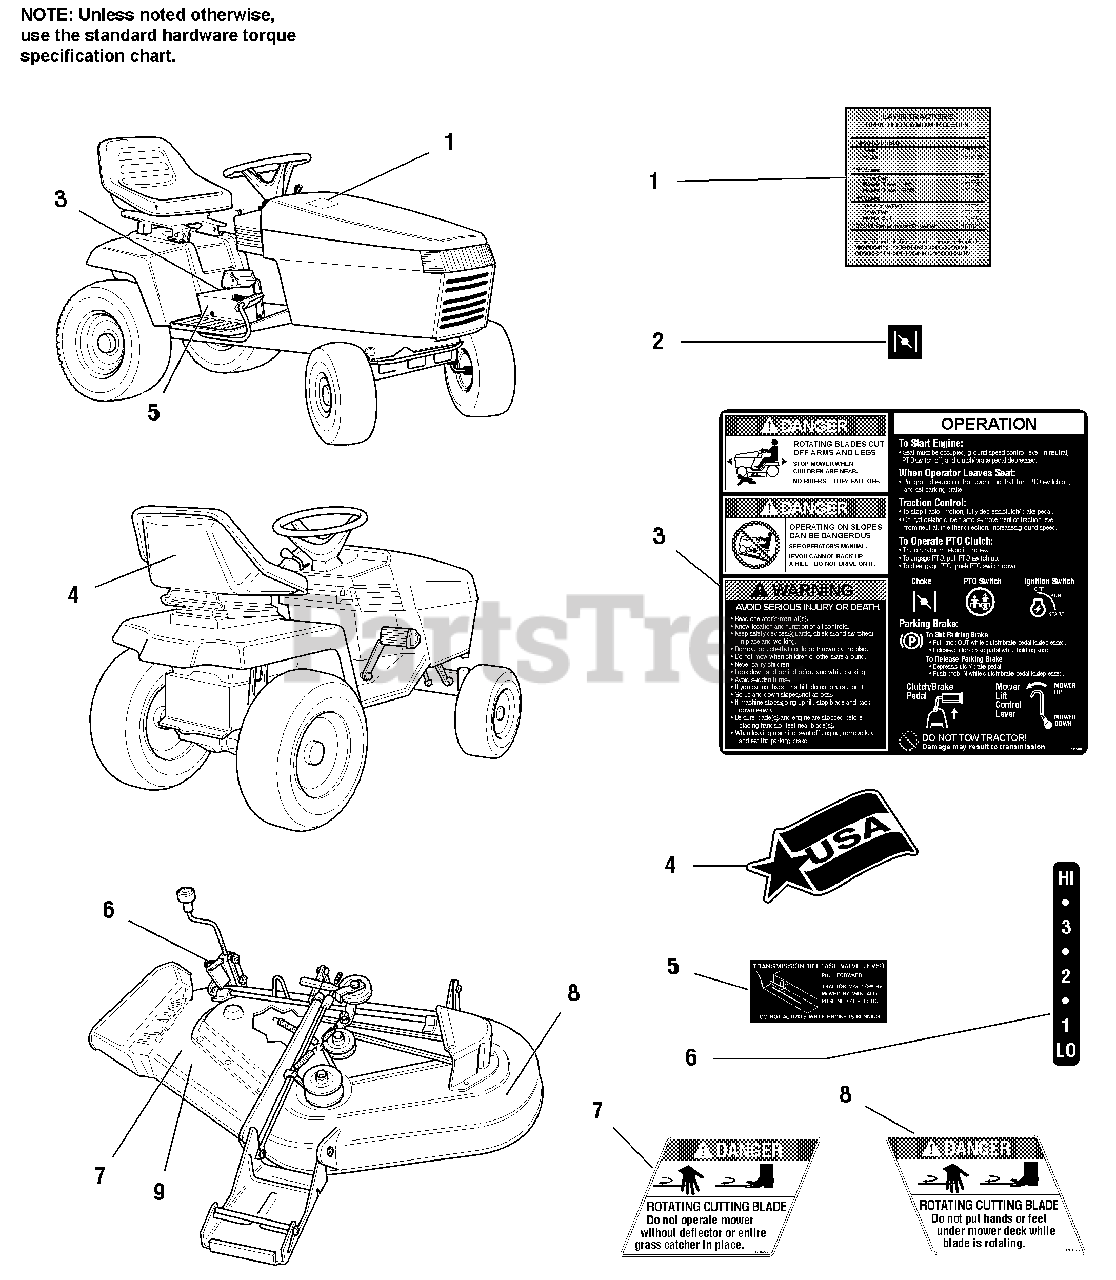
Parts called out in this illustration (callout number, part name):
1	DECAL, Belt, Blade
2	DECAL, Choke, Dash
3	DECAL, Operating Instructions
4	DECAL, USA Logo
5	DECAL, Transmission Release Valve
6	DECAL, Mower Height
7	DECAL, Danger (Chute in place)
8	DECAL, Danger (Hand under deck)
9	DECAL, Cutting Width 38"
9	DECAL, Cutting Width 44"
9	DECAL, Cutting Width 50"
